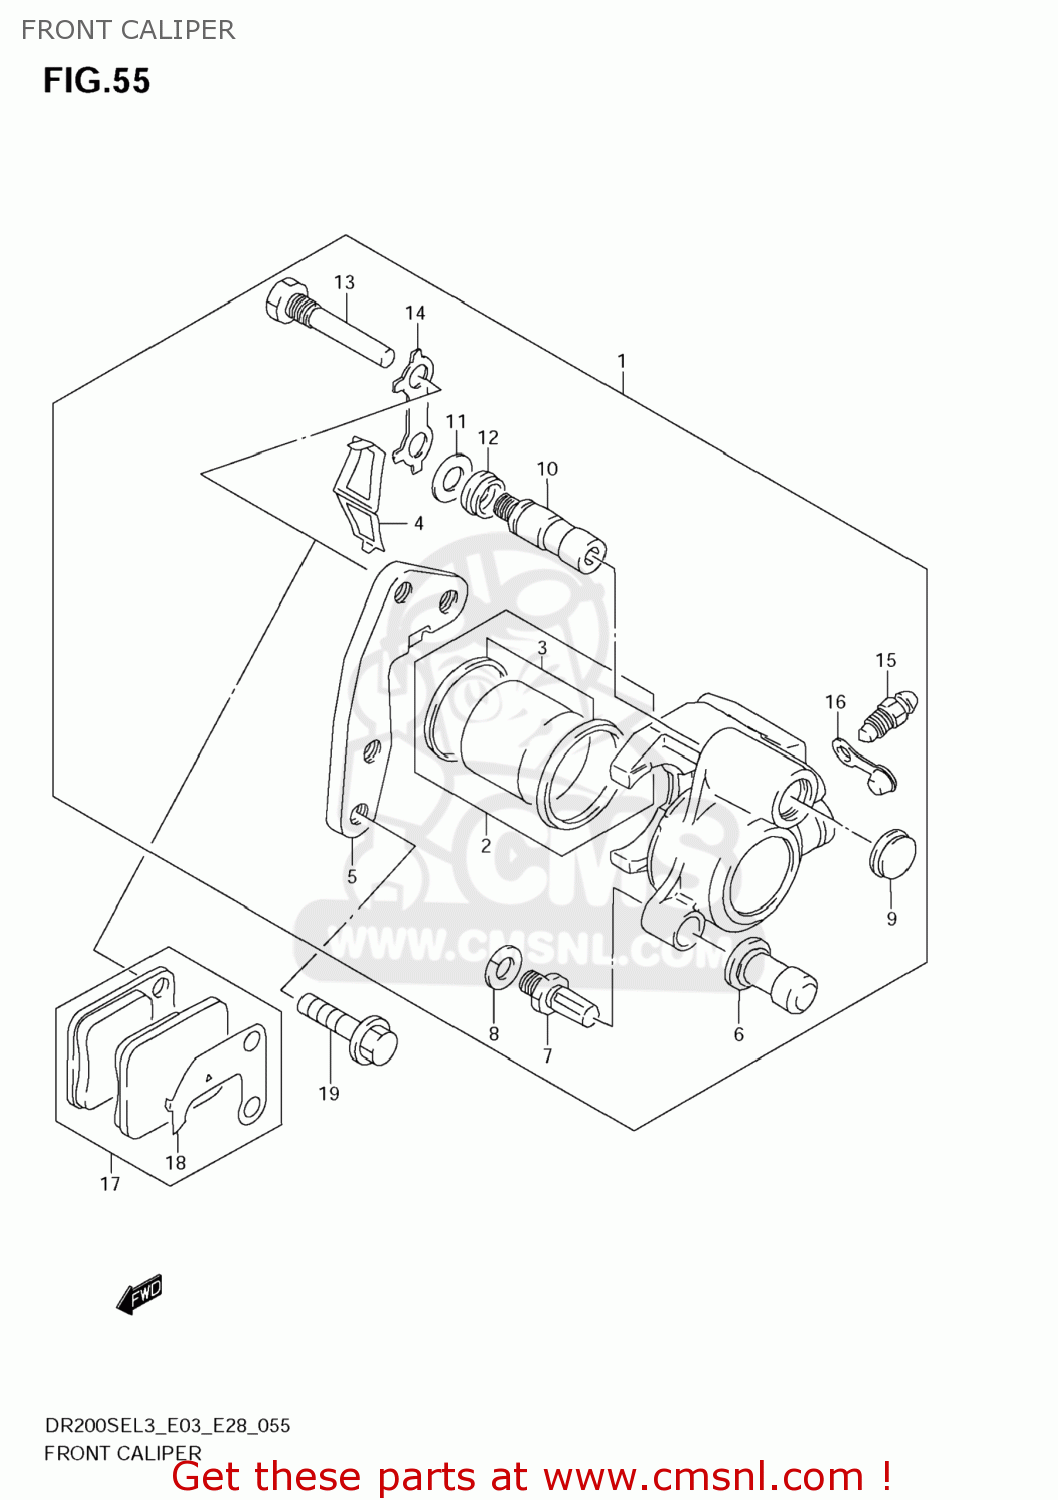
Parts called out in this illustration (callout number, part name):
1	CALIPER ASSY,FR,L
2	PISTON SET,CALIPERS
3	SEAL SET,PISTON
4	SPRING,PAD
5	BRACKET
6	BOOT
7	BOLT,PIN
8	WASHER,WAVE
9	DUST SEAL
10	PIN,SLIDE
11	SPRING,FRICTION
12	BOOT,PIN
13	PIN,HANGER
14	WASHER
15	BLEEDER
16	CAP,BLEEDER
17	PAD & SHIM SET (NAS)
18	SHIM
19	BOLT(8X30)
